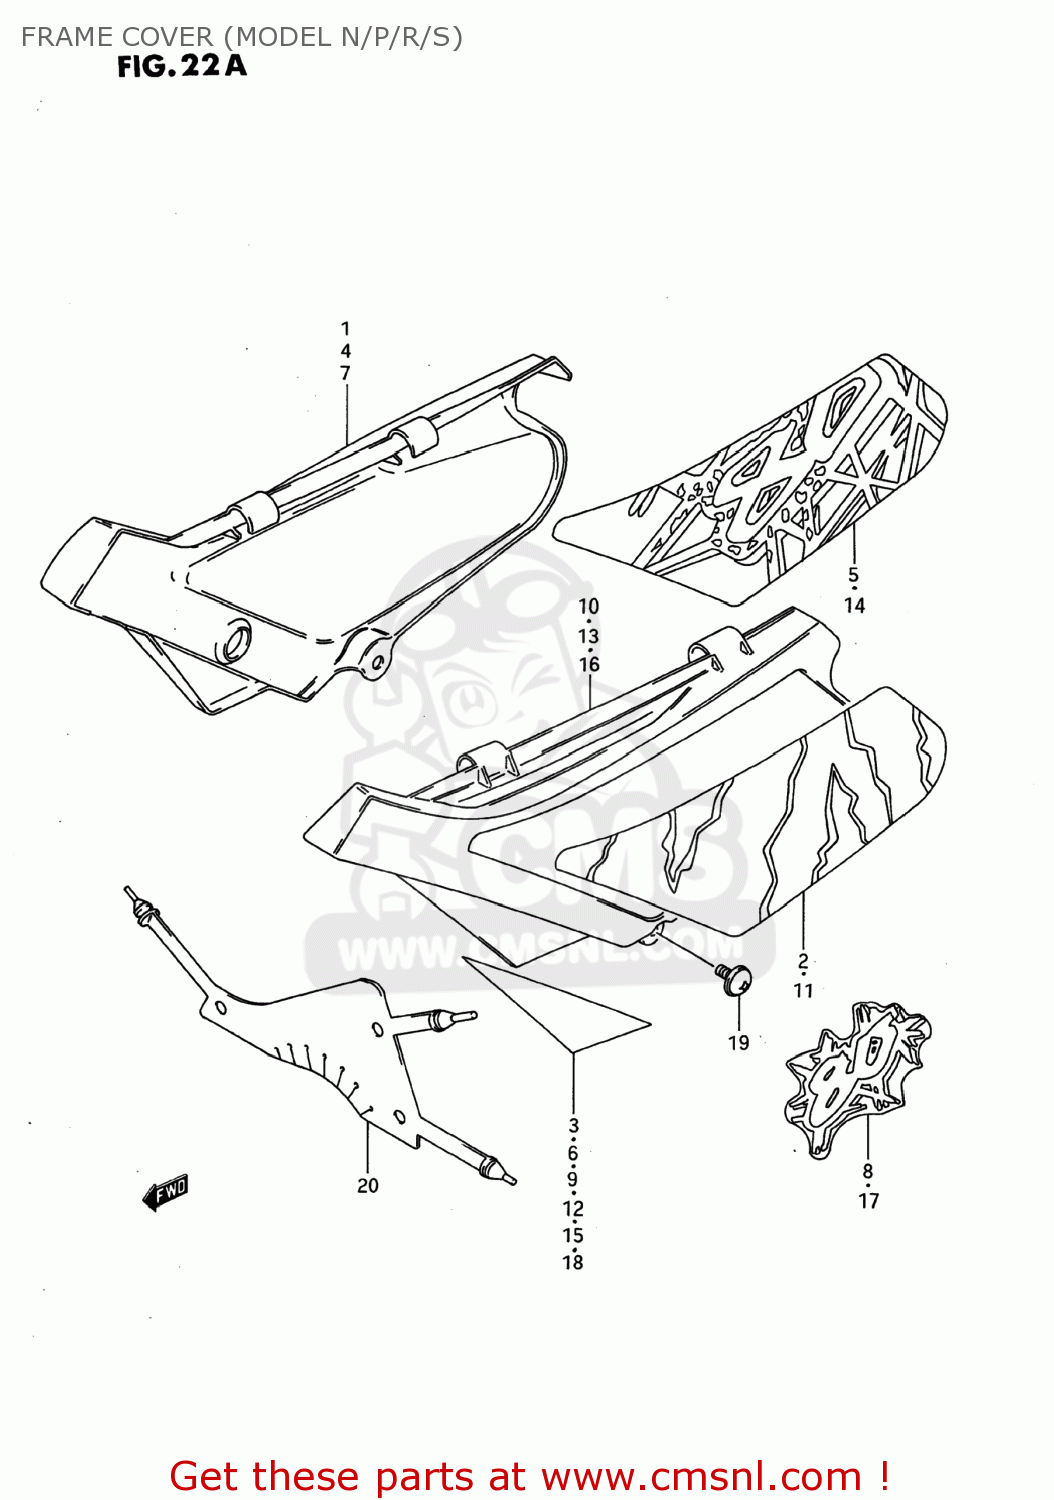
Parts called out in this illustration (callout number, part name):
1	COVER,FRAME,RIGHT
2	TAPE,FRAME COVER,RIGHT
3	TAPE,FRAME COVER NO.2,R
4	COVER,FRAME,RIGHT
5	TAPE,FRAME COVER,RIGHT
6	TAPE,FRAME COVER NO.2,R
7	COVER,FRAME,RIGHT
8	EMBLEM,FRAME COVER
9	TAPE,FRAME COVER NO.2,R
10	COVER,FRAME,LEFT
11	TAPE,FRAME COVER,LEFT
12	TAPE,FRAME COVER NO.2
13	COVER,FRAME,LEFT
14	TAPE,FRAME COVER,LEFT
15	TAPE,FRAME COVER NO.2
16	COVER,FRAME,L(WHITE)
17	EMBLEM,FRAME COVER
18	TAPE,FRAME COVER NO.2
19	SCREW(6X16)
20	MUD GUARD,FRAME COVER
